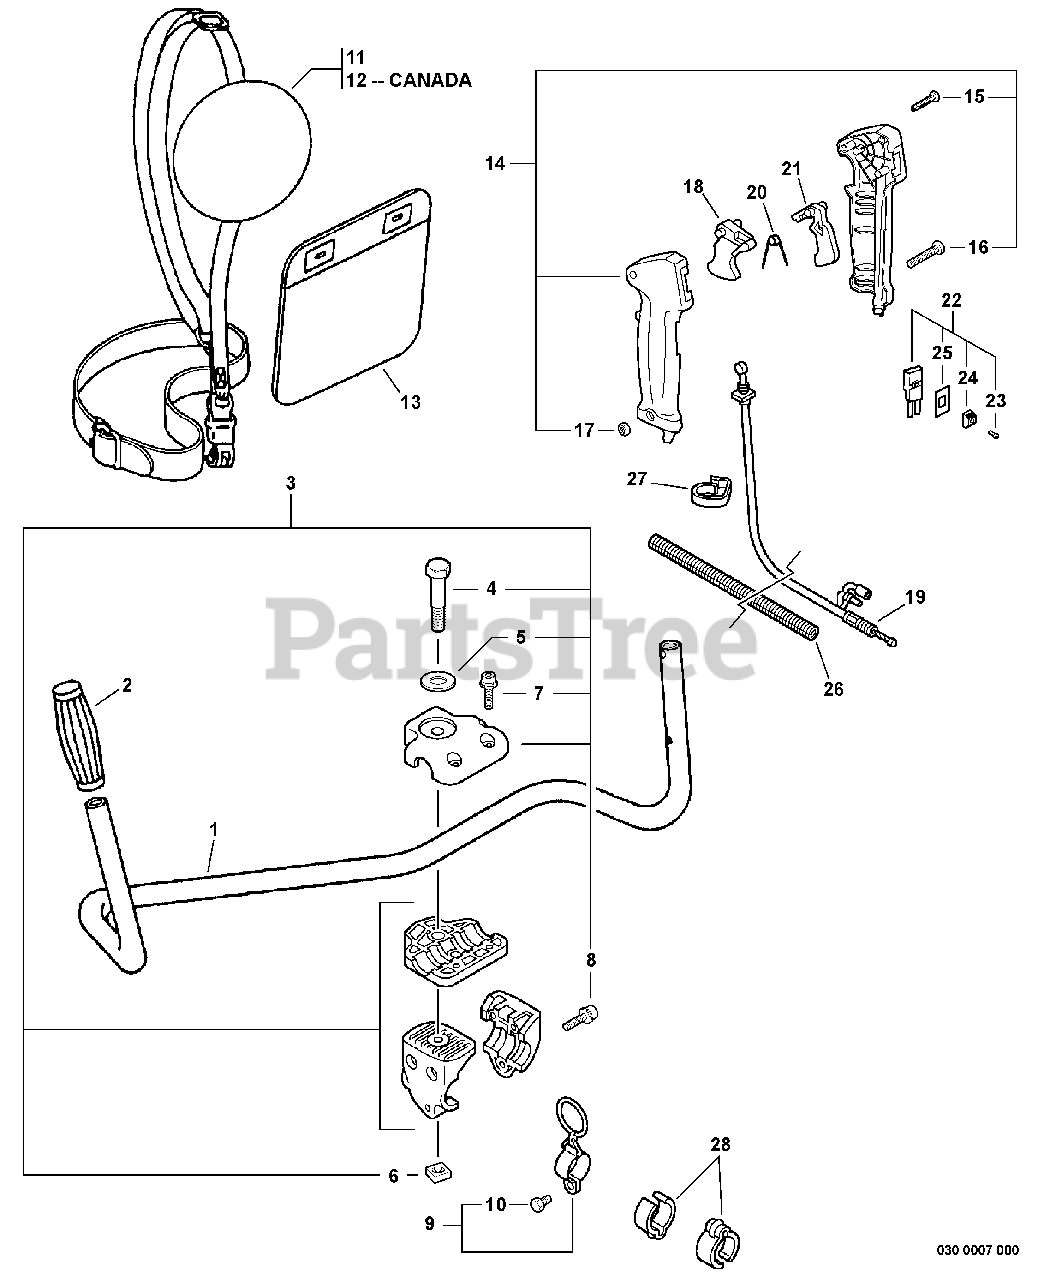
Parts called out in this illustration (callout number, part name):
1	HANDLE - FRONT
2	GRIP, HANDLE - LEFT
3	HANDLE BRACKET KIT
4	BOLT - 8X55
5	WASHER - 8
7	SCREW - 5X20
8	SCREW - 5X30
9	HANGER KIT
10	BOLT - 5X12
11	HARNESS ASSY
12	HARNESS ASSY
13	CUSHION
14	THROTTLE CONTROL ASSY
15	SCREW - 3X25
16	SCREW - 5X30
18	TRIGGER, THROTTLE
19	CABLE, THROTTLE
20	SPRING, LOCKOUT LEVER
21	LOCKOUT, THROTTLE
22	IGNITION SWITCH ASSY
23	SCREW - 3X10
24	KNOB, SWITCH - ORANGE
25	COVER, SWITCH - STOP
26	TUBE, PROTECTIVE - CORRUGATED
